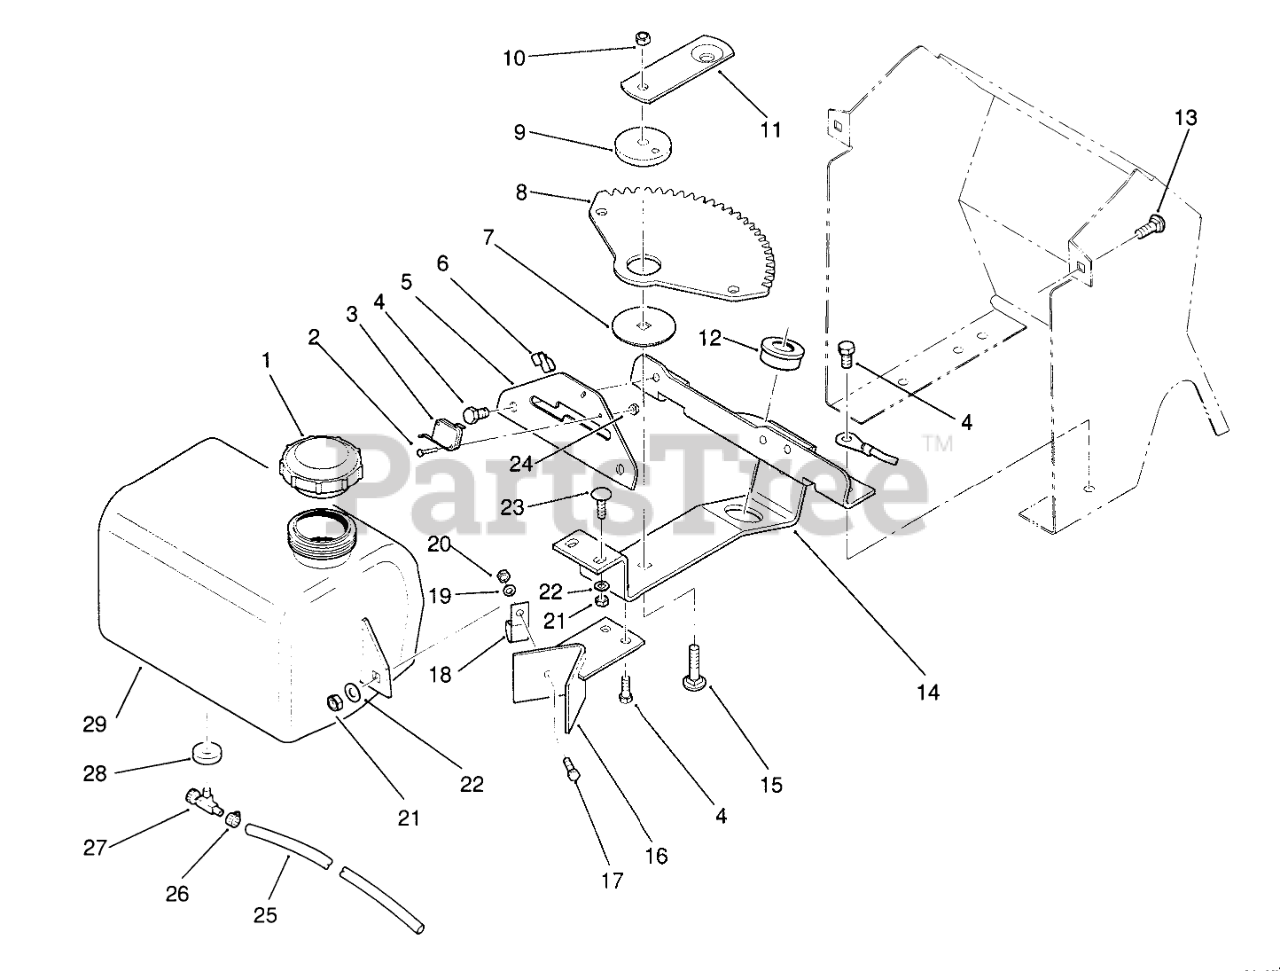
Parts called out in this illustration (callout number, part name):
1	CAP GAS
2	Screw
3	SWITCH - CLUTCH
4	Screw
5	PLATE-SHIFT R
6	CLIP-CABLE
7	WASHER-BEARING
8	GEAR-SECTOR
9	BUSHING
11	Plate
12	BEARING-WHEEL
13	Bolt-Carriage
14	STEERING BRKT - W/A R
15	Bolt-Carriage
16	Stop
17	Bolt
18	CLIP
20	Nut
21	Nut
22	WASHER 5/16 SAE
23	Bolt-Carriage
24	NUT HEX 4-40 ELAST
25	S/A FUEL HOSE 6554
26	Clamp
27	VALVE-FUEL
28	BUSHING
29	Fuel Tank
